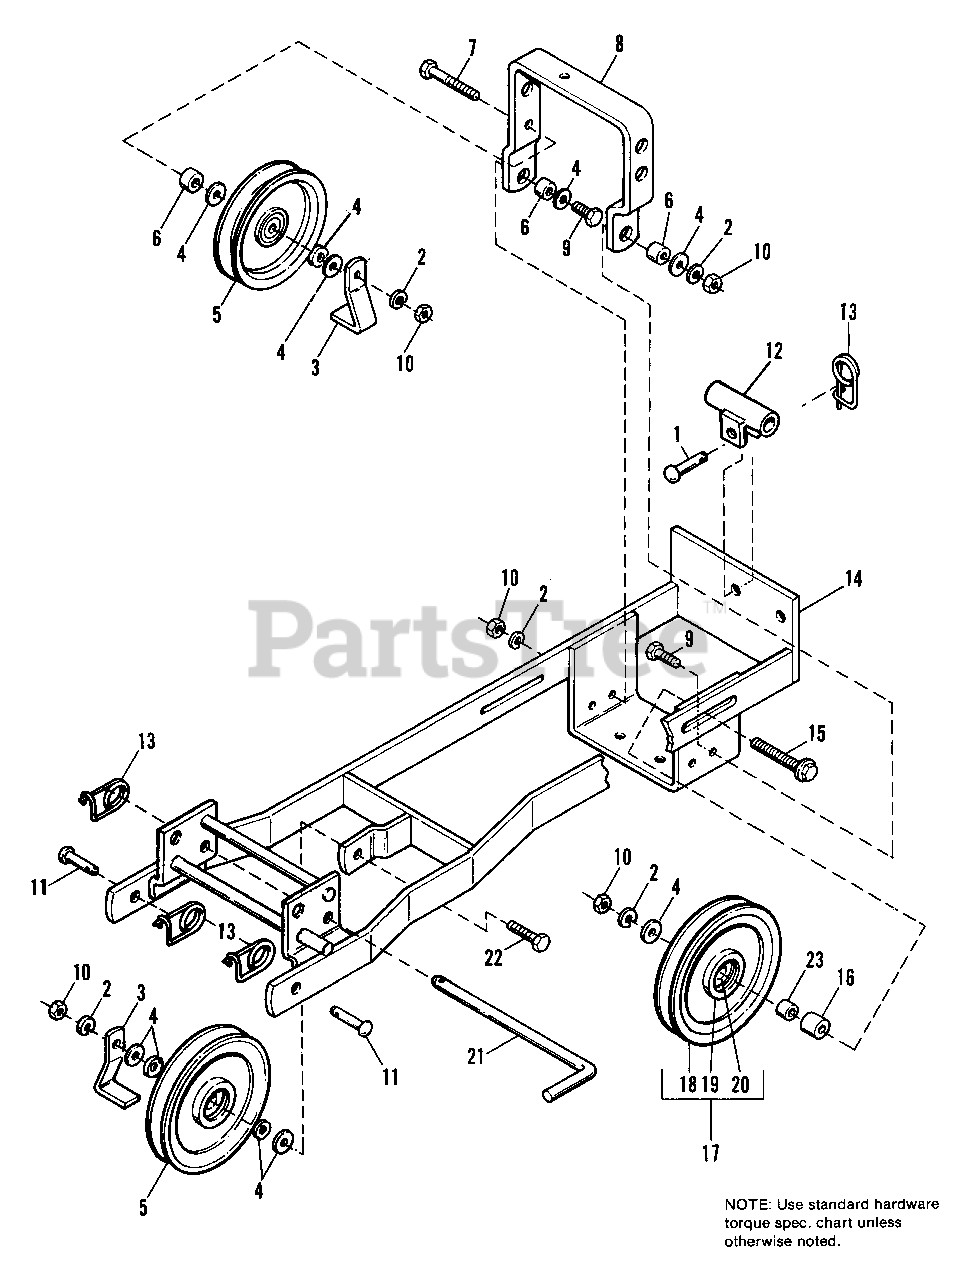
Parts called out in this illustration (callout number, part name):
1	PIN, Clevis
2	LOCKWASHER, 3/8
3	BELT STOP
4	WASHER, Plain, 5/16
7	CAPSCREW, 3/8-16 x 2-1/4
8	PIVOT, Bracket
9	CAPSCREW, 3/8-16 x 1-1/4
10	NUT, Hex, Full, 3/8-16
11	PIN, Clevis, 3/8
12	SUPPORT ARM., Rear
13	CLIP, Spring
14	PUSHBAR ASSY.
15	SCREW, Whizlock, 3/8-16 x 2-3/4
17	PULLEY ASSY., w/Bearing (Incl. Ref. Nos. 18, 19, 20)
19	RING, Retaining
22	CAPSCREW, 3/8-16 x 1-3/4
